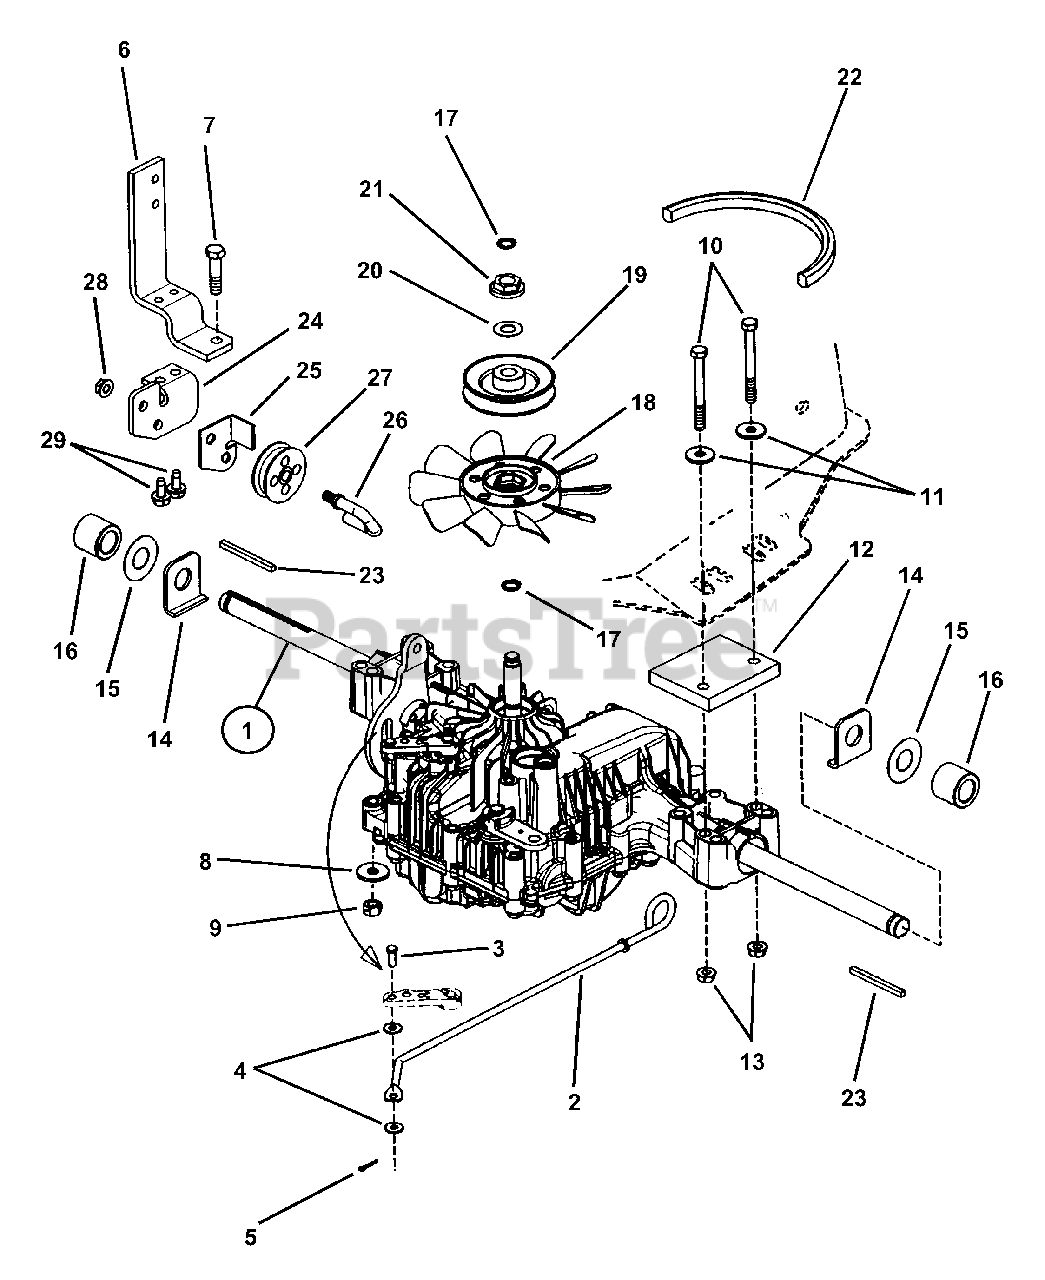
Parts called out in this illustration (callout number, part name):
1	ASSEMBLY, Transaxle, Tuff Torq
2	ROD, Roll Release (K46)
3	PIN, Clevis 1/4" x 5/8"
4	WASHER, 1/4 x 5/8 x 1/16" Flat
5	PIN, 3/32" x 1/2" Cotter
6	BRACKET, Torque
7	SCREW, 3/8-16 x 1-1/2" Hex Head Cap, Grade 5
8	WASHER, 5/16 x 11/16 x 1/16", Grade 5
9	NUT, 3/8-16 Hex Center Lock
10	SCREW, 5/16-18 x 3-1/4" Hex Head Cap, Grade 5
11	WASHER, 5/16" Flat
12	SPACER, Hydro Axle- K46
13	NUT, 5/16-18 Hex Flange Lock Grade 5
14	WASHER, Axle
15	WASHER, Thrust
16	SPACER, Axle
17	RING, E 15 (Vendor # 192154-89090)
18	FAN (Vendor # 1A640-83050)
19	PULLEY, 4" Diameter (Vendor # 1A6460-25333)
20	WASHER, Wave (Vendor # 1A6460-83060)
21	SPACER (Vendor # 1A6460-25300)
22	BELT, Traction Drive (HA Section, 97.881 Effective Length) (MY 2000)
22	BELT, Traction Drive (HA Section, 95.60 Effective Length) (MY 2001)
23	KEY, 3/16" Square x 2-3/16" long
24	BRACKET, Spool
25	GUIDE, Cable
26	ROD, Spool Pivot
27	SPOOL
28	NUT, 5/16-18 Hex Flange Lock, Grade 5
29	SCREW, 5/16-18 x 5/8" Hex Washer Self-Tap
